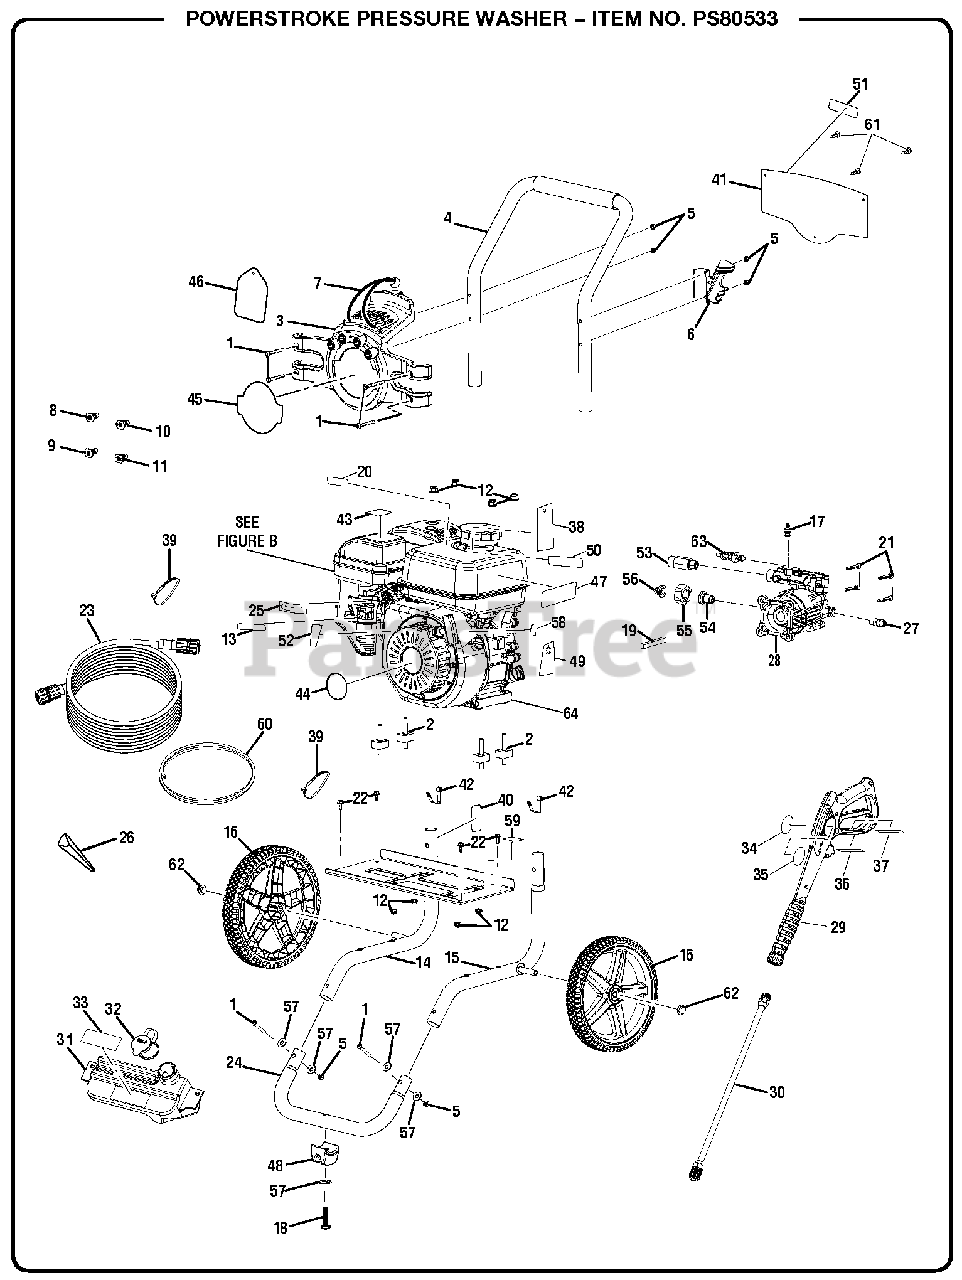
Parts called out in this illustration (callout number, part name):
1	Screw (M6 x 48 mm, T30 Torx Hd.)
2	Engine Isolator
3	Hose and Nozzle Holder Assembly
4	Handle w/Foam
5	Lock Nut (M6)
6	Wand Holder
7	Bungee Cord Assembly
8	40deg Nozzle
9	Soap Nozzle
10	25deg Nozzle
11	0deg Nozzle
12	Flange Nut (M8 x 1.25)
13	Fuel On-Off Label
14	Main Frame Assembly (Left)
15	Main Frame Assembly (Right)
16	Wheel
17	Detergent Suction Kit
18	Bolt (M6 x 25 mm, T30 Torx Hd.)
19	Output Shaft Key (40 mm)
20	Do Not Mix Label
21	Bolt (5/16-24 x 23 mm, Soc.Hex Hd.)
22	Flange Bolt (M6 x 16 mm)
23	Hose (25 ft.)
24	Front Frame
25	Choke Label
27	Thermal Release Valve
29	Trigger Handle Assembly
30	Extension Wand
31	Soap Tank
32	Soap Tank Cap
33	Soap Dilution Label
34	Label (Wand Logo)
35	Warning Label (En)
36	Warning Label (Fr/Sp)
37	Label (Wand Rating)
38	Danger Hangtag
40	Combustion Warning Label
41	Quick Start Panel
42	Lock Button w/Spring Clip
43	Hot Surface Label
44	Recoil Label
45	Performance Label
46	Nozzle Hangtag
47	Danger Label
48	Rubber Foot
49	Dipstick Hangtag
50	No E85 Label
51	Inquiries Label
52	Fuel Valve Label
53	Outlet Tube
56	Filter Screen (Pump Inlet)
57	Washer (1/4 in.)
58	Engine On/Off Label
59	Oil Fill Location Label
60	Chemical Siphon Tube
61	Screw (#6-20)
62	Push Cap Nut
63	Unloader Valve Assembly
64	Engine
